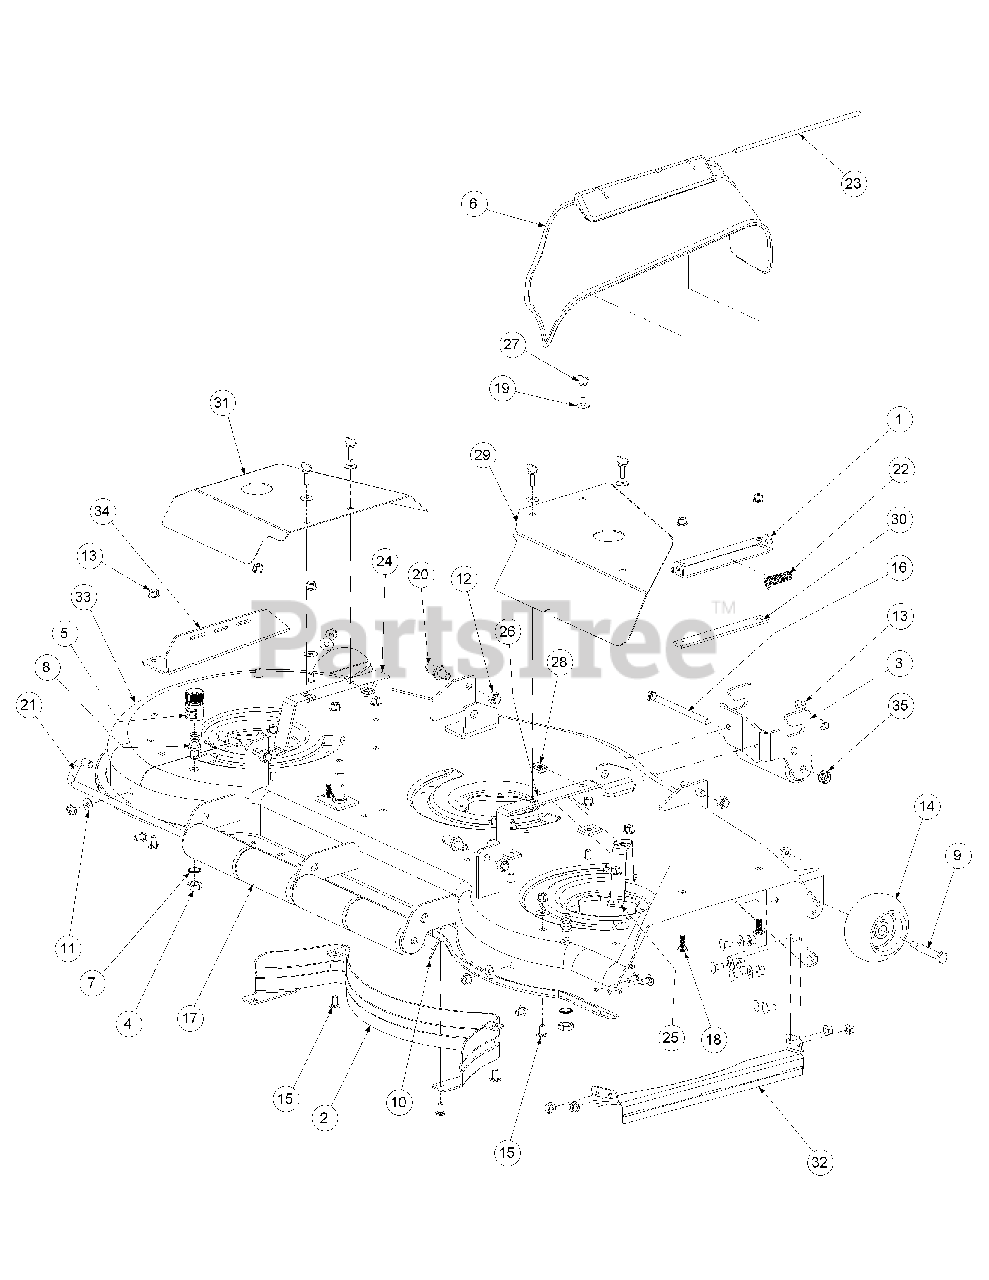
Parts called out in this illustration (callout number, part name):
1	Chute Deflector Bracket
2	Deck Baffle
3	Front Roller Bracket
4	Hex Nut, M16-1.5
5	Water Nozzle Adaptor
6	Chute Deflector
7	Lock Washer, 17 x 23.8 x 1.9
8	Nozzle, Deck Water
9	Shoulder Screw .498 x 1.53
10	Cotter Pin, .125 Dia. x 1.0
11	Flat Washer, 3/8
12	Lock Nut, Nylon Insert, 1/2-13
13	Hex Nut, 3/8-16, Flange Lock
14	Complete Wheel, 5.00 Dia
15	Carriage Bolt 3/8-16 x .75
16	Hex Cap Screw, 1/2-20 x 7.25
17	Front Roller
18	Carriage Bolt, 3/8-16 x 1.00
19	Washer, .325 x .930 x .045
20	Pin, 5/8 Dia x 1.2 Lg
21	Roller Pin
22	Torsion Spring
23	Chute Deflector Rod
24	Support Bracket Belt Cover Left Hand
25	Support Bracket Belt Cover Right Hand
26	Support Bracket Belt Cover Center
27	Thumb Screw, 5/16-18 x 1.0 Lg.
28	U Nut, 5/16-18
29	Belt Cover 60 Right Hand
30	Strip Spacer, 0.1875 Thick
31	Belt Cover 60 Left Hand
32	Finger Guard Assembly
33	Deck Assembly 60"
34	Belt Cover Support Bracket
35	Nut, 1/2-20, Nylon Insert
